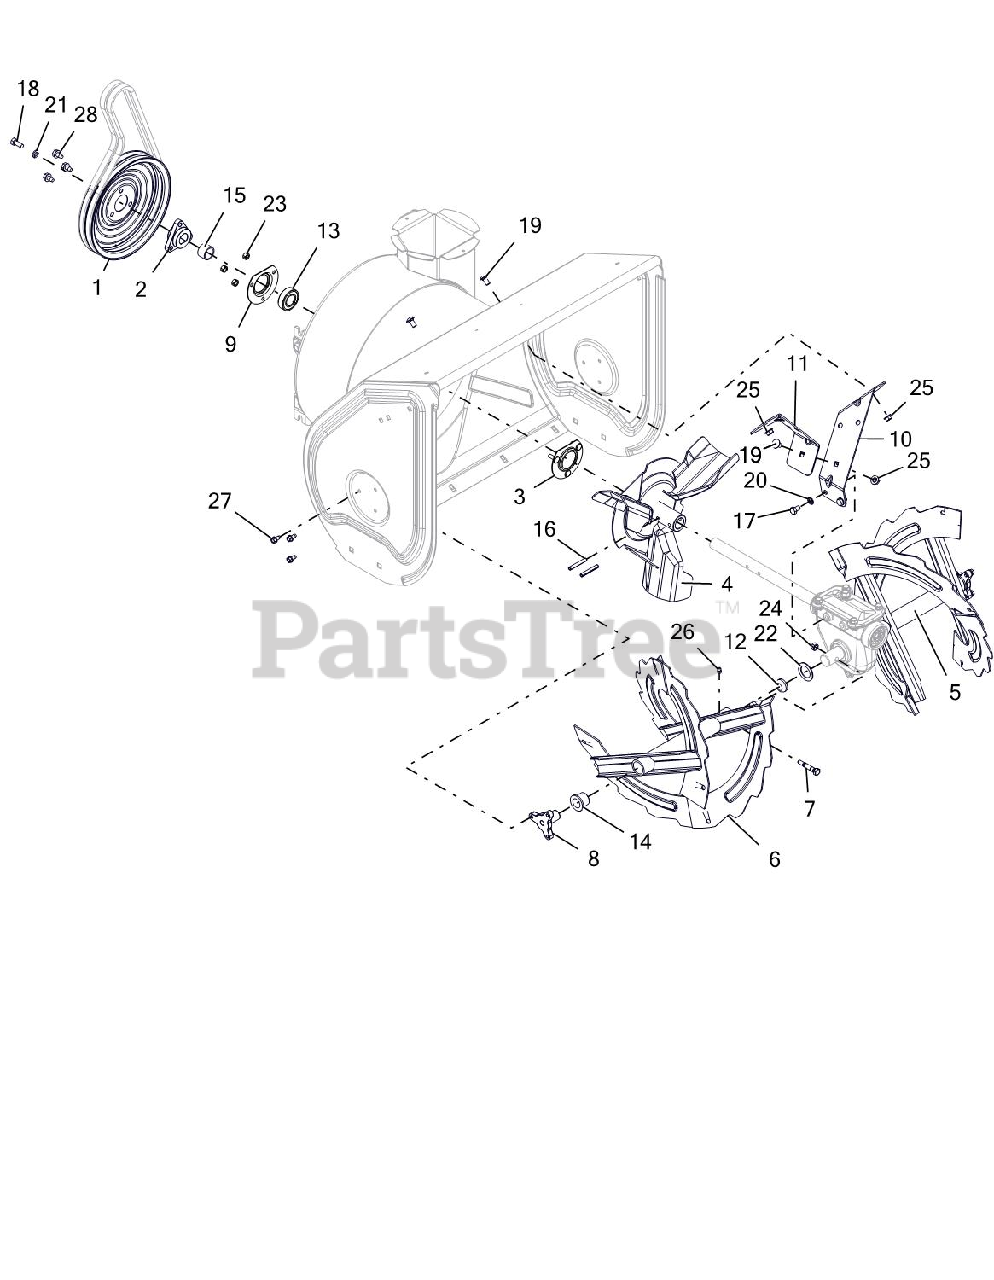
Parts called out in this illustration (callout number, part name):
1	PULLEY, SPIN FORM DUAL GROOVE
2	PULLEY HUB, D-BORE .87 DELUXE
3	BEARING FLANGE
4	IMPELLER, 3 BLADE-14"
5	RAKE, LH W/ZERK - 24"
6	RAKE, RH W/ZERK - 24"
7	SHEAR BOLT SERVICE ASSEMBLY
8	SUPPORT, RAKE BUSHING
9	BEARING FLANGE
10	BRACKET, GEARCASE SUPPORT - LH
11	BRACKET, GEARCASE SUPPORT - RH
12	PLUG, RAKE TUBE
13	BRG-BALL .876 X 1.750 X .50
14	BSHG-FLG, NY.778 ID X 1.018 OD
15	BSHG,SPCR .895X1.065X.693
16	PIN-ROLL .250X1.75
17	@BLT-HEX .31-18X.50 GR5 YWZC
18	BLT-HEX .31-24X.75 YWZC GR5
19	BLT-RDHDSQSHNK.31-18X.62 YZ-LK
20	@WSHR-LK-EXT.326X.599X.031YWZC
21	WSHR-LK .312X.097 HVY YWZC
22	WSHR-FL-STL 1.010X1.505X.062YZ
23	@NUT-LK-CTR .25-20 YWZC
24	@NUT-LK-CTR .31-18 YWZC
25	@NUT-LK-TOP-FLG .31-18 YWZC
26	ZERK,FITTING .25X.125 DRIVE IN
27	SCR-TAP .25-20X.50 HWH TR YWZ
28	@SCR-TAP .31-18X.50 HWH TR YWZ
